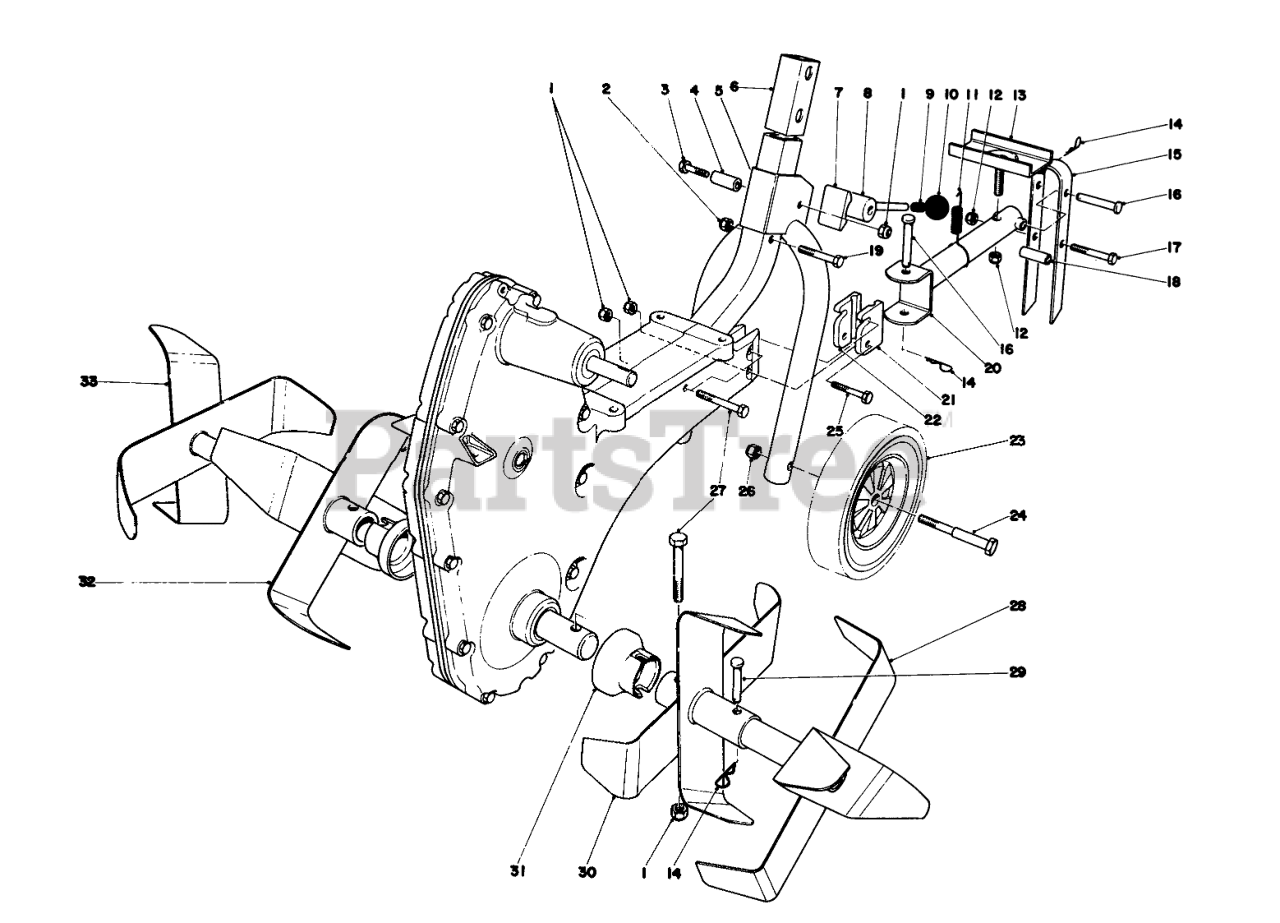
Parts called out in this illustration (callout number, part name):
1	NUT-HEX, SIDE DEFORM
2	NUT-HEX, SIDE DEFORM
3	SCREW-HH
4	CAM SPACER
5	Wheel Support
6	Lower Handle
7	Cam Shoe
8	Cam Lever
9	Tolerance Ring
11	Spring
12	NUT-LOCK, SIDE
13	Drawbar Stop
14	PIN-COTTER
15	Dragbar
16	PIN-CLEVIS
17	SCREW-HH
18	Spacer
19	SCREW-HH
20	Drawbar
21	LH PIVOT BLOCK
22	Pivot Block R.H.
23	Valve Lever
24	Wheel Bolt
25	SCREW-HH
26	NUT-LOCK, CONE
27	SCREW-HH
28	Outboard Tine L.H.
29	CLEVIS
30	Inboard Tine L.H.
31	Dust Cover
32	Inboard Tine R.H.
33	Outboard Tine R.H.
